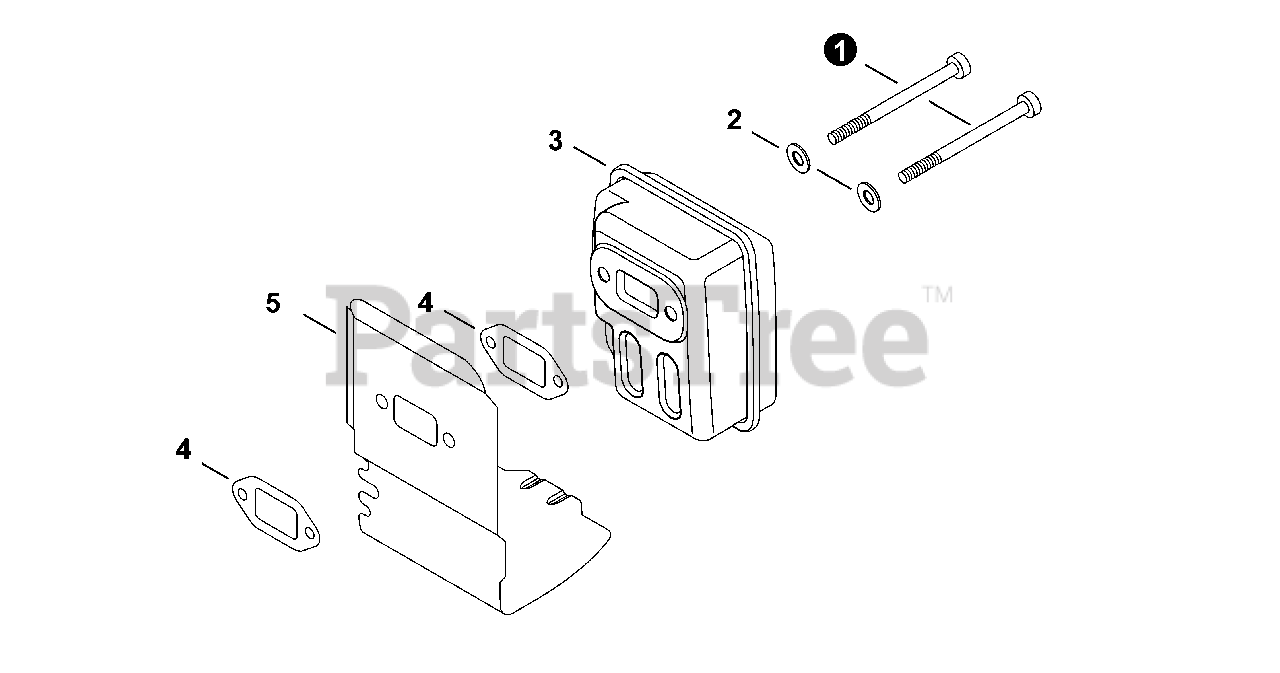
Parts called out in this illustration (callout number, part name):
1	BOLT 5×55
2	WASHER, FLAT 5.5×10×0.8
3	MUFFLER
4	GASKET, EXHAUST
5	HEAT SHIELD, EXHAUST
